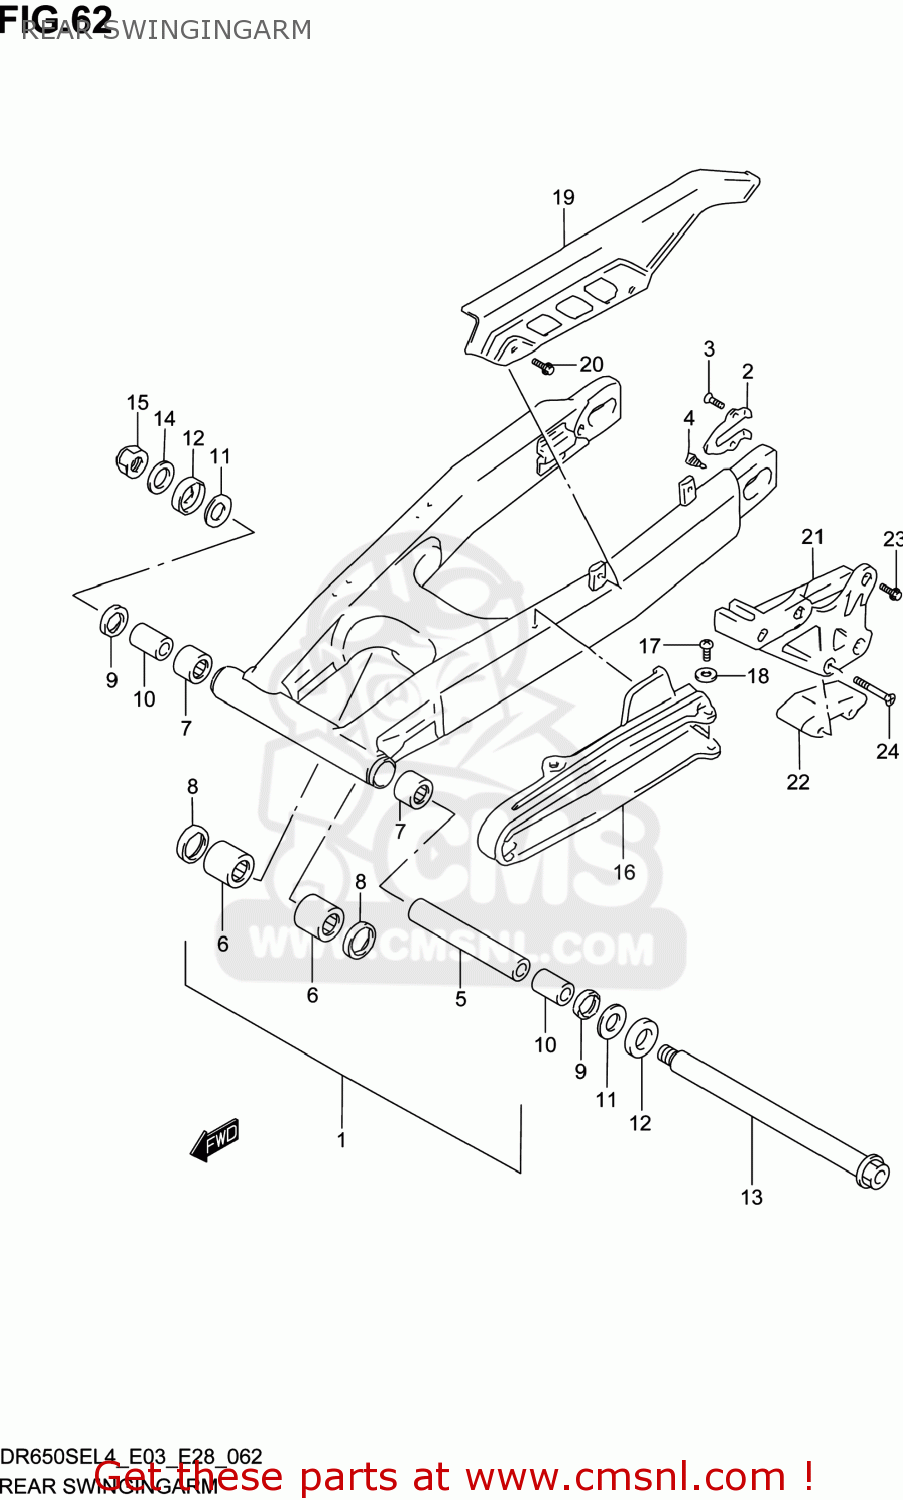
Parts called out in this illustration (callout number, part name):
1	SWINGINGARM ASSY,RR
2	PLATE,RR SWING ARM AXLE
3	SCREW(5X8)
4	STOPPER,CHAIN ADJUSTER
5	SPACER,SWGARM PIVOT CTR
6	BEARING(20X27X23.5)
7	BEARING(22X29X30)
8	SEAL,OIL(20X27X5)
9	SEAL,OIL(22X29X4)
10	SPACER,SWGARM PIVOT BRG
11	WASHER
12	COVER,SWINGINGARM PIVOT
13	AXLE,RR
14	WASHER
15	NUT
16	BUFFER,CHAIN TOUCH DEFENSE
17	SCREW
18	WASHER
19	CASE,CHAIN
20	BOLT(6X10)
21	GUIDE,CHAIN
22	DEFENSE,CHAIN GUIDE
23	BOLT
24	SCREW
